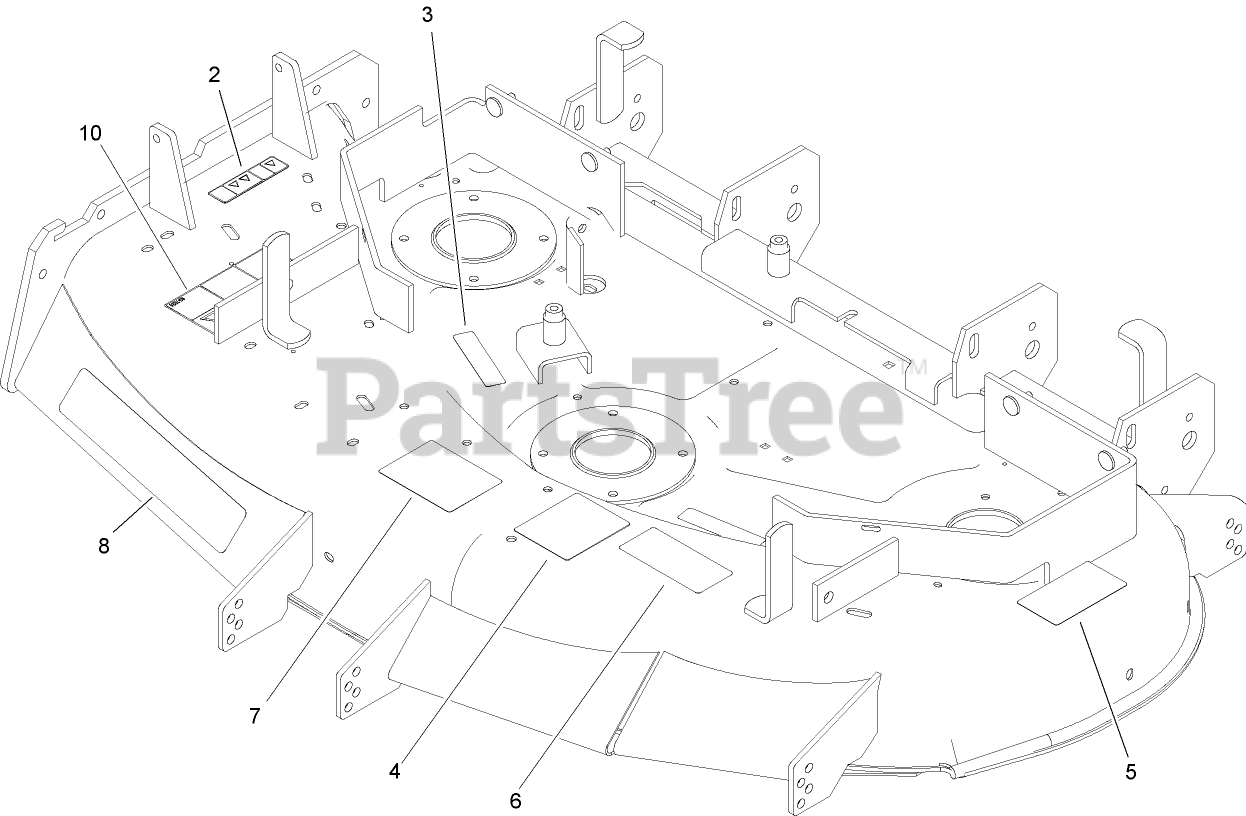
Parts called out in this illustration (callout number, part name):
2	DECAL-WARNING, DEFLECTOR
3	DECAL-WARNING
4	DECAL-ROUTING, BELT
5	DECAL-DANGER
6	DECAL-TORQUE, BLADE BOLT
7	DECAL-ANTI SCALP
10	DECAL-DANGER
